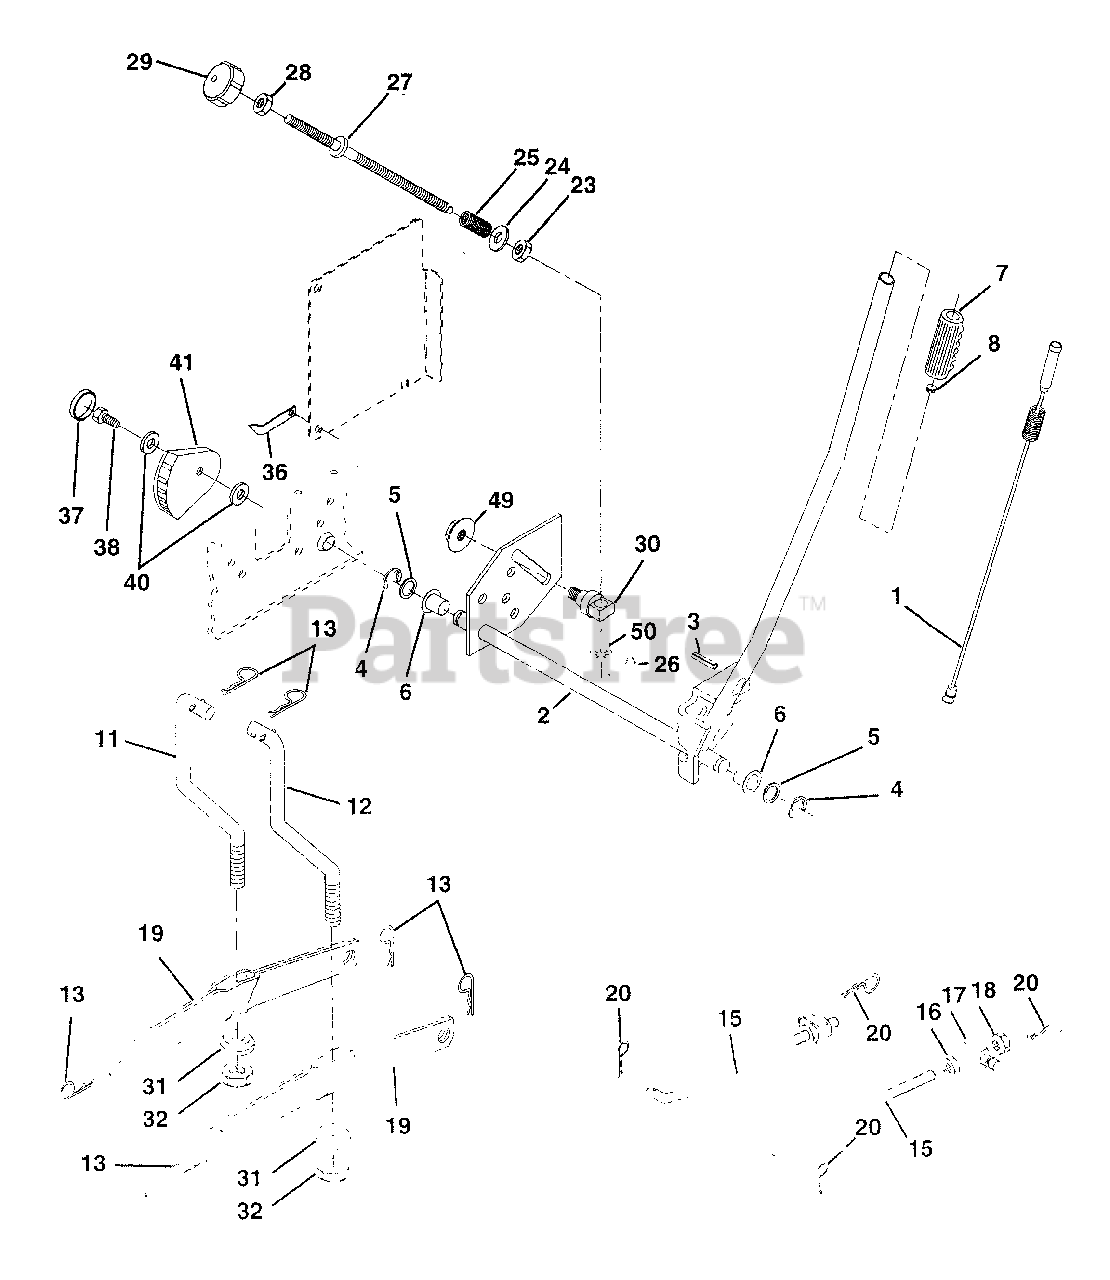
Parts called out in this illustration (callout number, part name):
1	Wire Asm Inner/Sprg W/plunger Lt
2	Shaft Asm Lift RH w/Inf
3	Pin Groove 1 500 Zinc
4	E Ring #5133-62
5	Washer 21/32 X 1 X 21 Ga
6	Bearing Nylon Blk 629 Id
7	Grip Handle Fluted Blk
8	Button Plunger Black
11	Link Lift LH Fixed Length
12	Link Lift RH Fixed Length
13	Retainer Spring
15	Link Front
16	Nut Jam Hex 1/2-13 Unc
17	Trunnion Blk Zinc
18	Nut Lock W/wsh 1/2-13unc
19	Arm Suspension Rear
20	Retainer Spring
23	Nut Special
24	Washer 13/32 X 5/8 X 16 Ga
25	Spring 2-1/8"
26	Pin Cotter 3/32 X 1/2
27	Rod Adj Lift Zinc 7.49 Wrk Lg
28	Nut Hex Jam 3/8-16 Unc
29	Knob Inf 3/8-16 Unc Blk W/sym
30	Trunnion Infin Height
31	Bearing Pvt Lift Spherical
32	Nut Crownlock 3/8 - 24
36	Indicator Height STLT
37	Plug Hole Blk 1.485/1.515 Dia.
38	Screw Thdrol 5/16-18 x 3/4
40	Washer 11/32 x 1-1/2 10 Ga.
41	Scale Ind, Height Blk.
49	Nut Hex Flange Lock
50	Nut Push Phos & Oil
